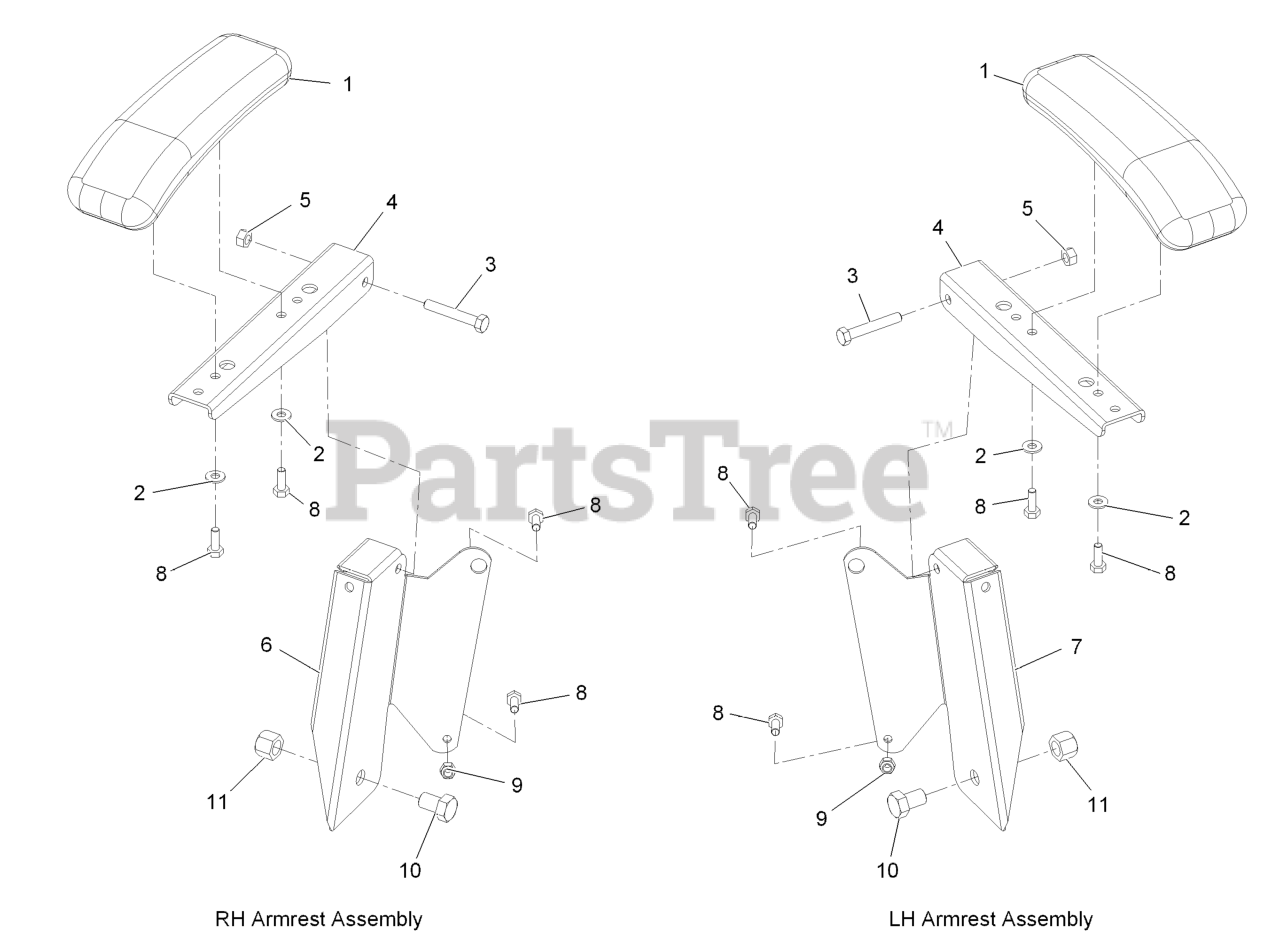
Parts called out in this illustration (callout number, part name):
1	CUSHION-REST, ARM
2	WASHER-FLAT
3	SCREW-HH
4	CHANNEL-ARMREST
5	NUT-HEX, SIDE DEFORM
6	BRACKET-ARMREST, RH
7	BRACKET-ARMREST, LH
8	SCREW-HH
9	NUT-LOCK, NI
10	SCREW-HH
11	NUT-LOCK, NI
